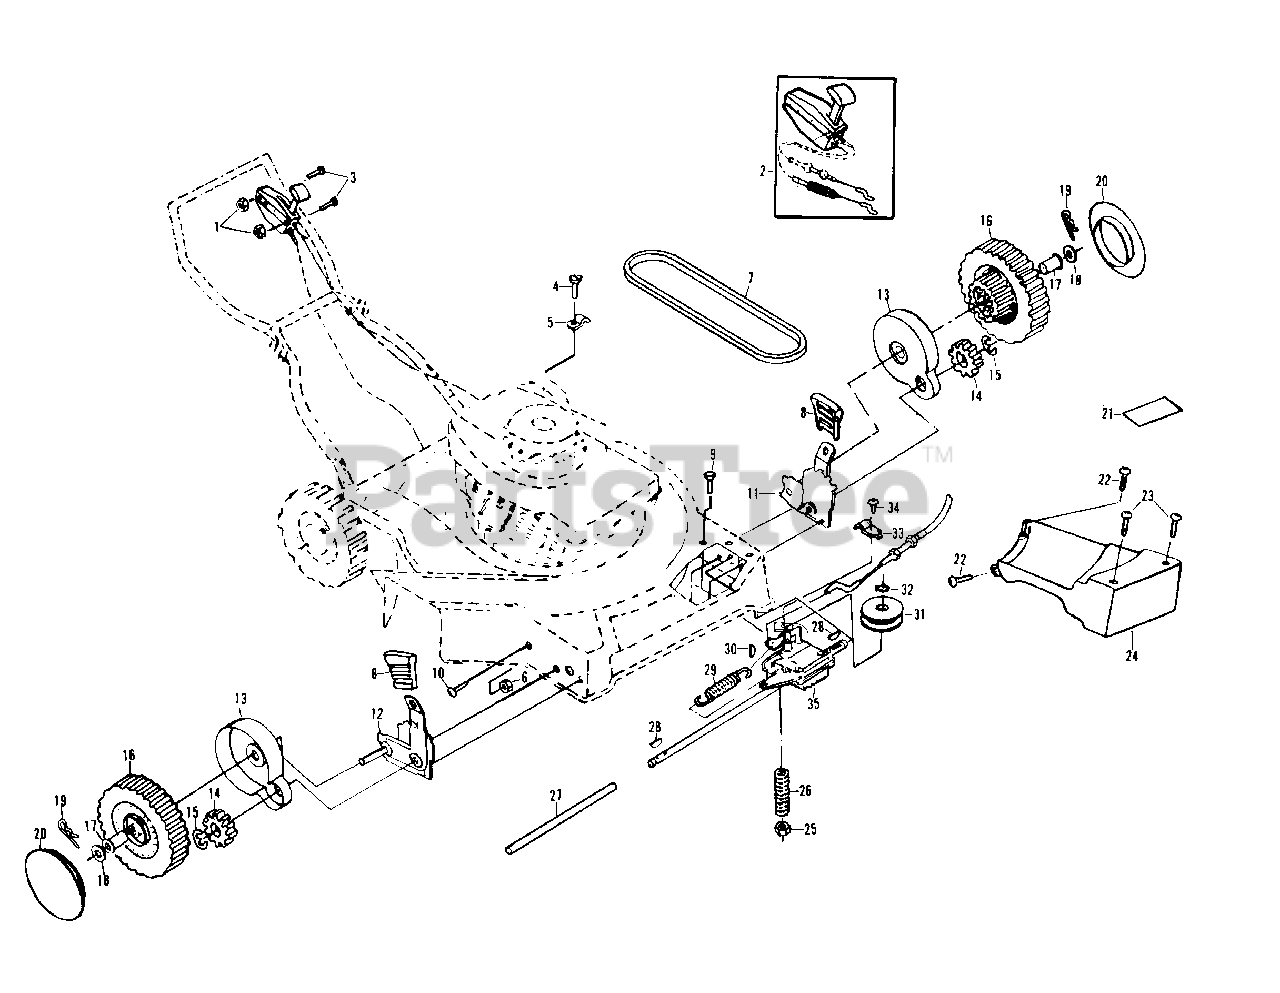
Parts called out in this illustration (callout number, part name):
1	Locknut (AYP part number)
2	Dual Head Control (Complete) (AYP part number)
3	Machine Screw (AYP part number)
4	Hex Washer Head Screw (AYP part number)
5	Guide Clip (AYP part number)
6	Locknut (AYP part number)
8	Selector Knob (AYP part number)
9	Hex Head Bolt (AYP part number)
10	Flat Head Machine Screw (AYP part number)
11	Wheel Adjuster Assembly (Left)
12	Wheel Adjuster Assembly (Right)
13	Dust Cover (AYP part number)
14	Pinion (AYP part number)
15	E-Ring (AYP part number)
16	Wheel & Tire Assembly (Front) (AYP part number)
17	Wheel Bushing (AYP part number)
18	Flat Washer (AYP part number)
19	Retainer Clip (AYP part number)
21	Drive Cover Decal (AYP part number)
22	Hex Washer Head Screw (AYP part number)
23	Pan Head Tapping Screw (AYP part number)
24	Drive Cover (AYP part number)
25	Locknut (AYP part number)
27	Drive Shaft Cover (AYP part number)
28	Woodruff Key #3 (AYP part number)
29	Spring (AYP part number)
30	Woodruff Key #213 (AYP part number)
31	Drive Pulley (AYP part number)
32	Retaining Ring (AYP part number)
33	Cable Clamp (AYP part number)
34	Hex Washer Head Tapping Screw (AYP part number)
35	Gear Case Assembly (Complete) (AYP part number)
